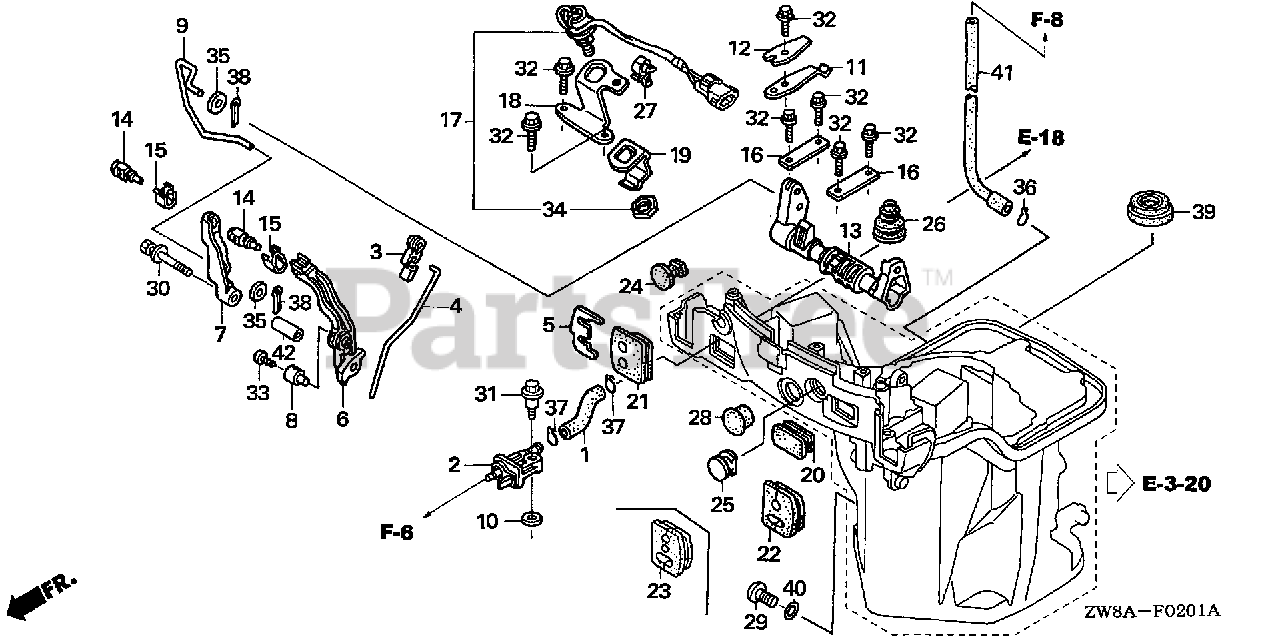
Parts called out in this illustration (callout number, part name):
1	TUBE A, FUEL
2	CONNECTOR ASSY., FUEL (B)
3	LINKAGE, PIVOT
4	ROD, THROTTLE
5	PLATE, REMOTE CONTROL CABLE
6	ARM, THROTTLE REMOTE
7	ARM, SHIFT LINK
8	HOLDER, THROTTLE ROD
9	ROD, SHIFT LINK
10	WASHER, PIVOT
11	SPRING, CLICK
12	SPRING, CLICK ASSIST
13	SHAFT, SHIFT
14	PIVOT, SHIFT
15	PLATE, LOCK
16	PLATE, SHIFT SHAFT
17	SWITCH SET, NEUTRAL
18	BRACKET, NEUTRAL SWITCH
19	PLATE, NEUTRAL SWITCH
20	GROMMET G, OIL CASE
21	GROMMET A, OIL CASE
23	GROMMET B, OIL CASE (PT)
24	GROMMET F, OIL CASE
25	GROMMET D, OIL CASE
26	GROMMET E, OIL CASE
27	CLIP, BRAKE PIPE (A)
28	CAP, HANDLE (LOWER)
29	BOLT, OIL CHECK
30	BOLT-WASHER (6X40)
31	BOLT, SPECIAL (6X22) (CT200)
32	BOLT, FLANGE (5X12) (CT200)
33	BOLT, RECESSED (5X8)
34	NUT, HEX. (20MM)
35	WASHER, PLAIN (7MM)
36	CLIP, TUBE (B10)
37	CLIP, TUBE (B12)
38	PIN, SPLIT (2.0)
39	SEAL, WATER (13X28X7)
40	O-RING (5.5X1.5)
41	TUBE, WATER CHECK
42	COLLAR, DISTANCE (6X11X27)
